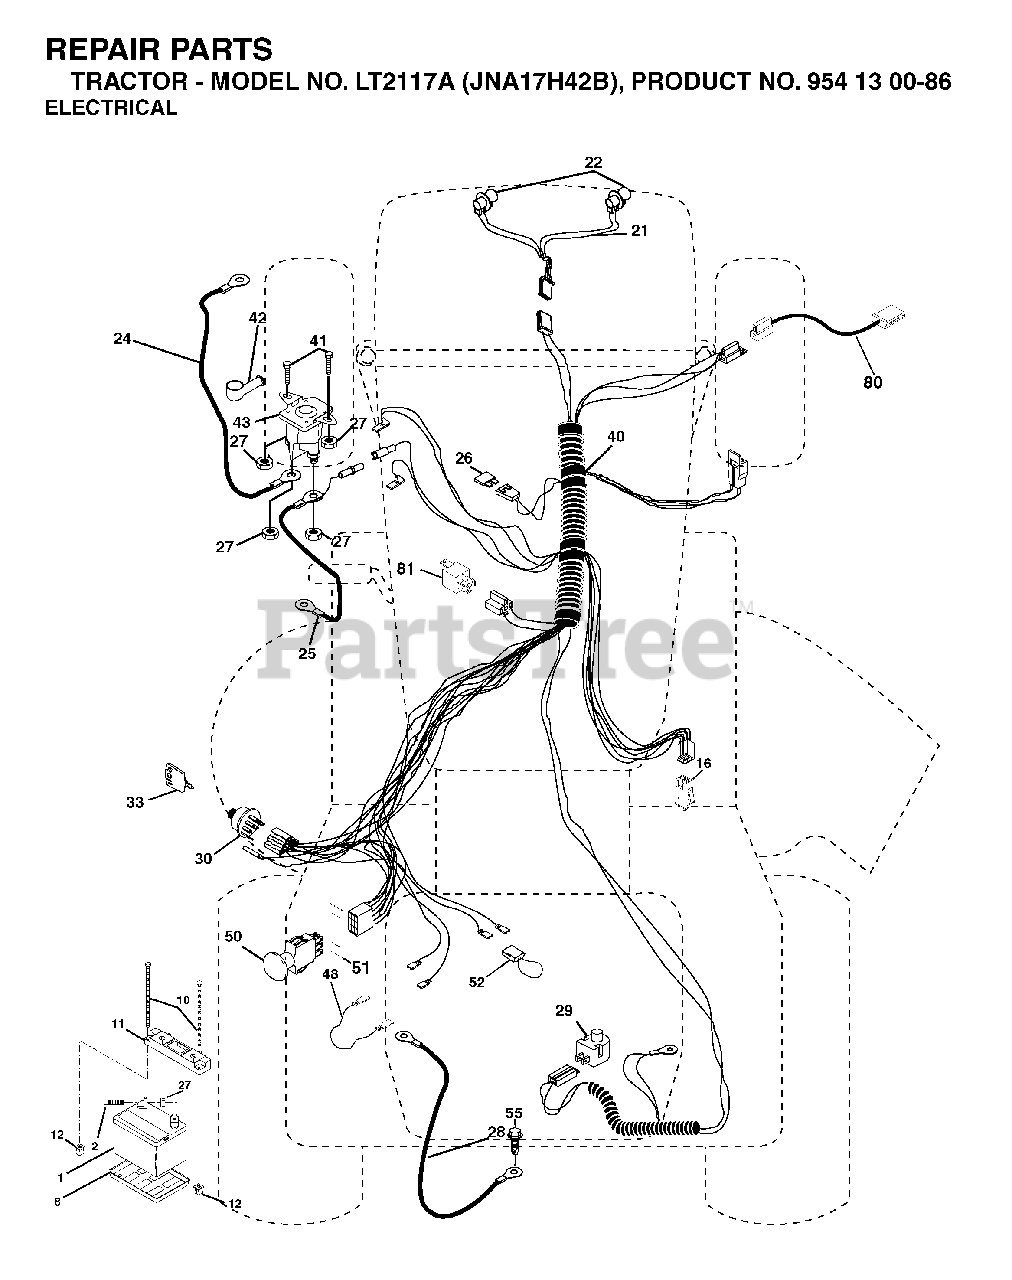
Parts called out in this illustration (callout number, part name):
1	REPL BY 532 12 38-99
8	BATTERY TRAY T
10	BOLT 1/4-20 X 7.5
11	BATTERY HOLDDOWN
12	NUT, PUSH NYLON 1/4" BATTERY
16	SWITCH INTERLOOK PUSH-IN
21	WIRE HARNESS
22	LIGHTBULB
24	BATTERY CABLE GT
25	CABLE BATTERY 6 GA 22" W/16W
26	FUSE 20AMP
27	NUT
28	CABLE GROUND 6 GA 21" 90T BLK
29	PLUNGER SWITCH (COLOR:OLIVE)
30	IGNITION SWITCH
33	KEY MLD GEN DELTA
40	HARNESS IGN.
42	TERMINAL COVER
43	SOLENOID
50	PTO SWITCH
51	RETAINING RING
52	WIRE PROTECTION LOOP
80	HARNESS, CLUTCH
81	RELAY.ASSY.T
